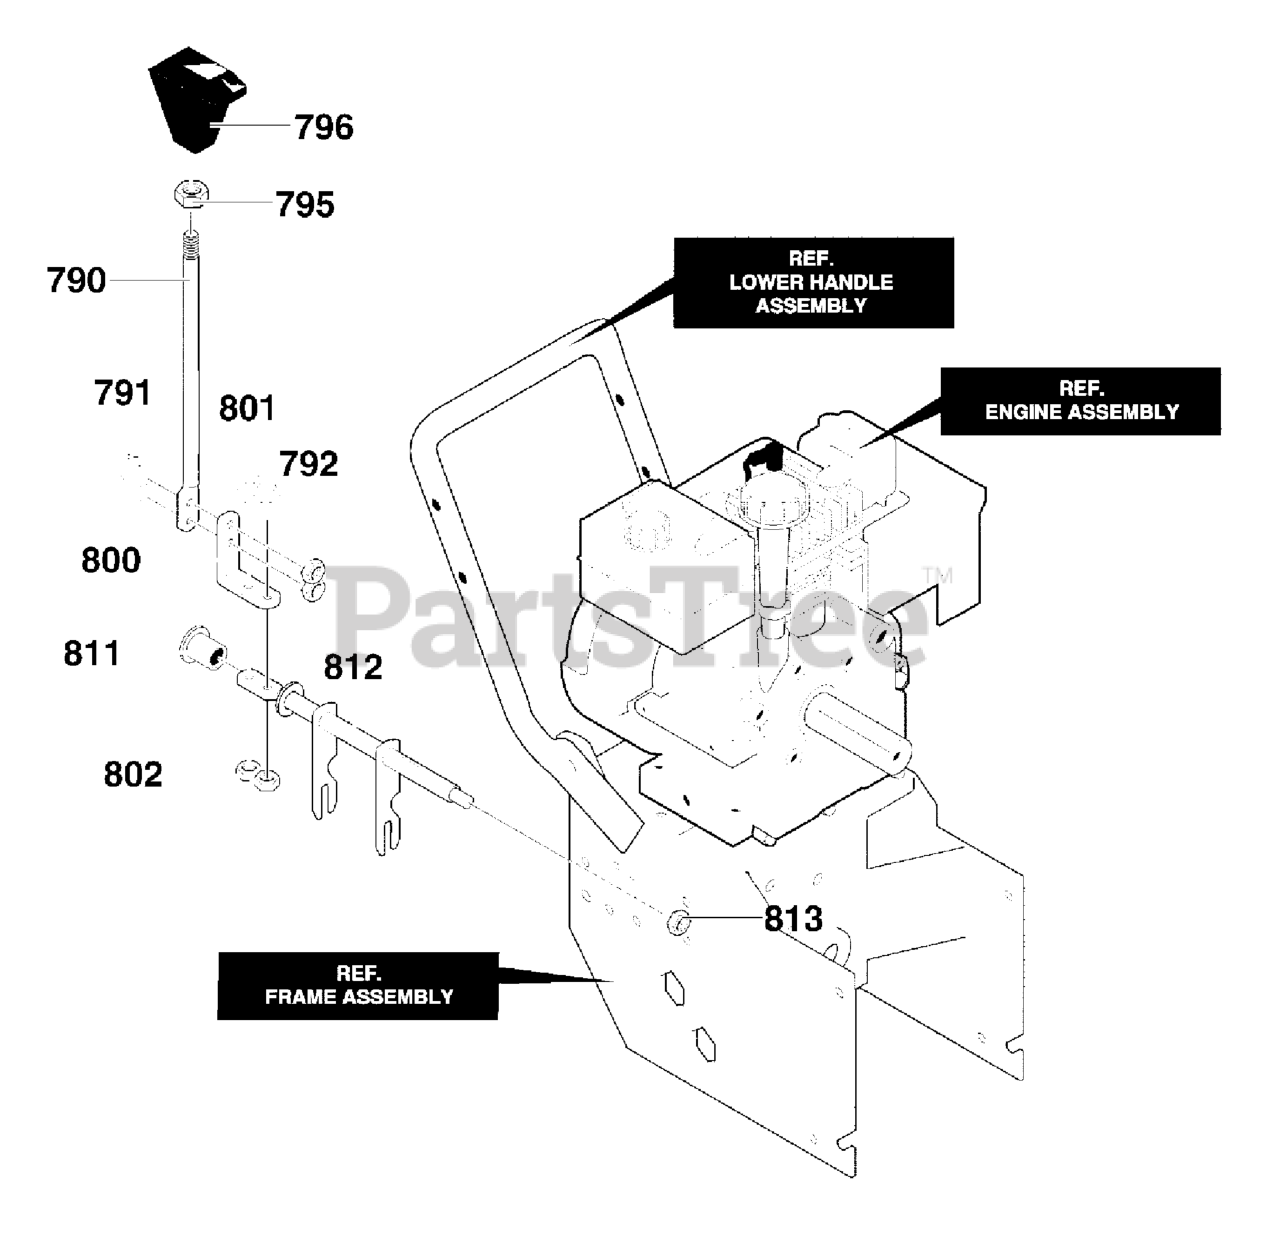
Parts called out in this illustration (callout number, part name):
790	ROD, SHIFT
791	SCREW, 1/4-20X.75
792	NUT, 1/4-20
795	NUT, 1/2-13 HEX JAM
796	KNOB, SHIFT
800	LEVER, SPRING SHIFT
801	SCREW, 1/4-20X.75
802	NUT, 1/4-20
811	BEARING, FLANGED
812	ROD, ASSY. YOKE
813	NUT, 3/8-16
